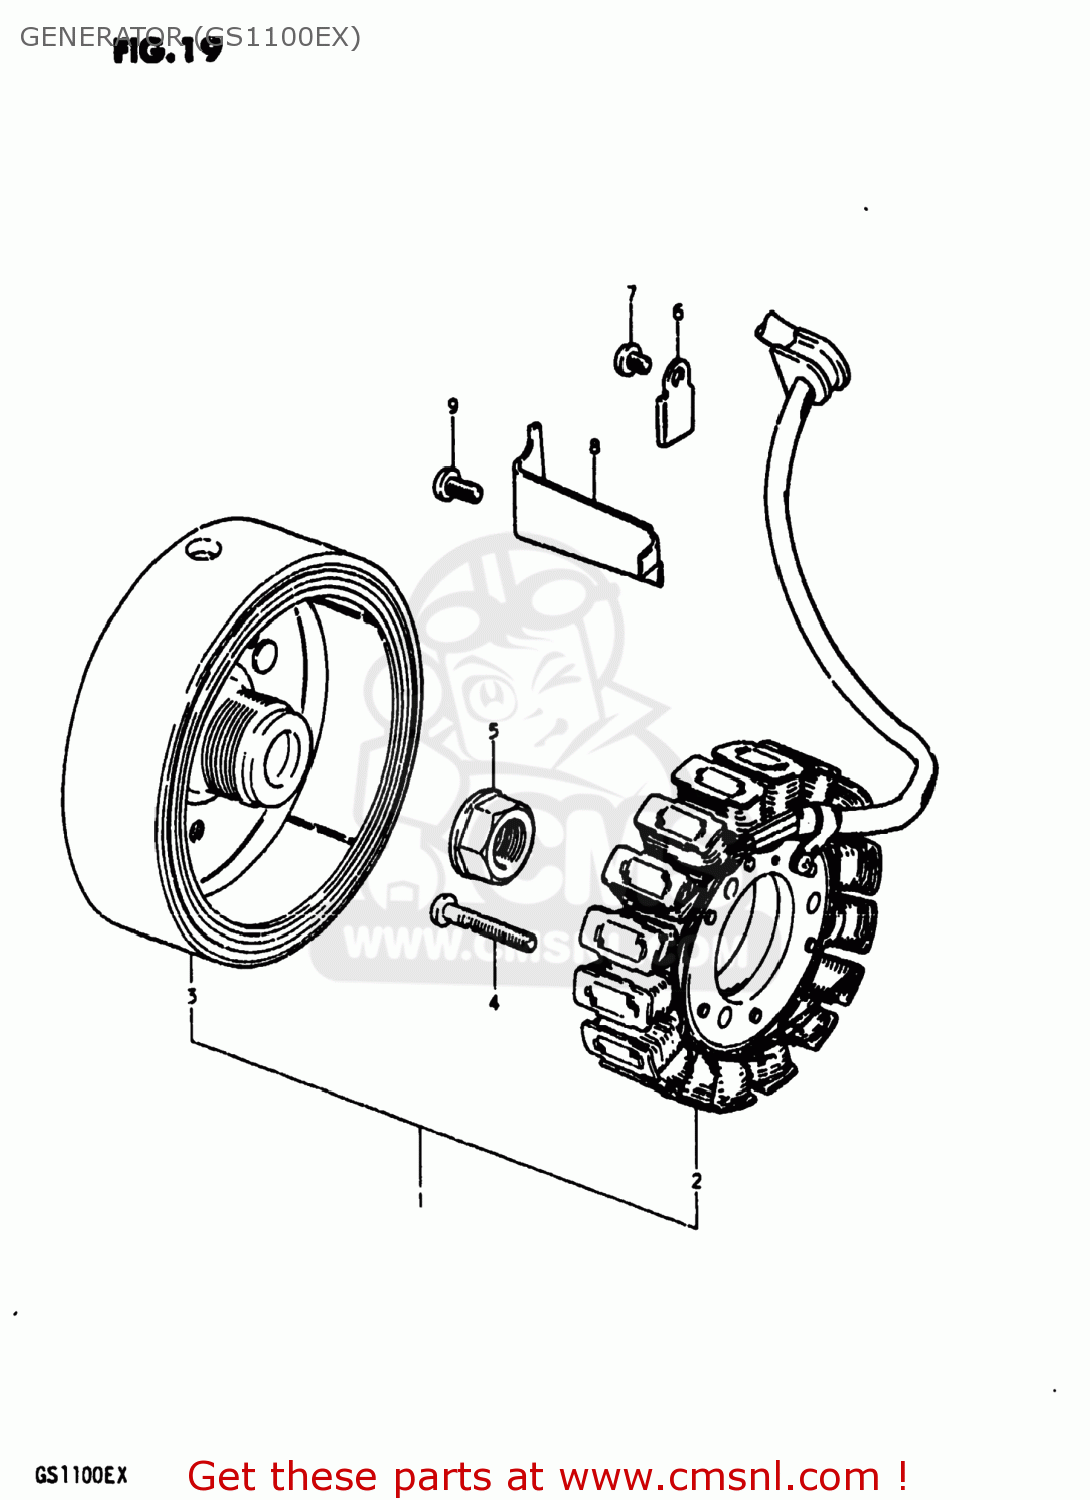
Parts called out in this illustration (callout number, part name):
1	GENERATOR ASSEMBLY
2	STATOR ASSEMBLY
3	ROTOR ASSY
4	SCREW 6X30
5	NUT,GENERATOR ROTOR
6	CLAMP,GENERATOR LEAD WIRE
7	SCREW
8	CLAMP,GENERATOR LEAD WIRE
9	SCREW
